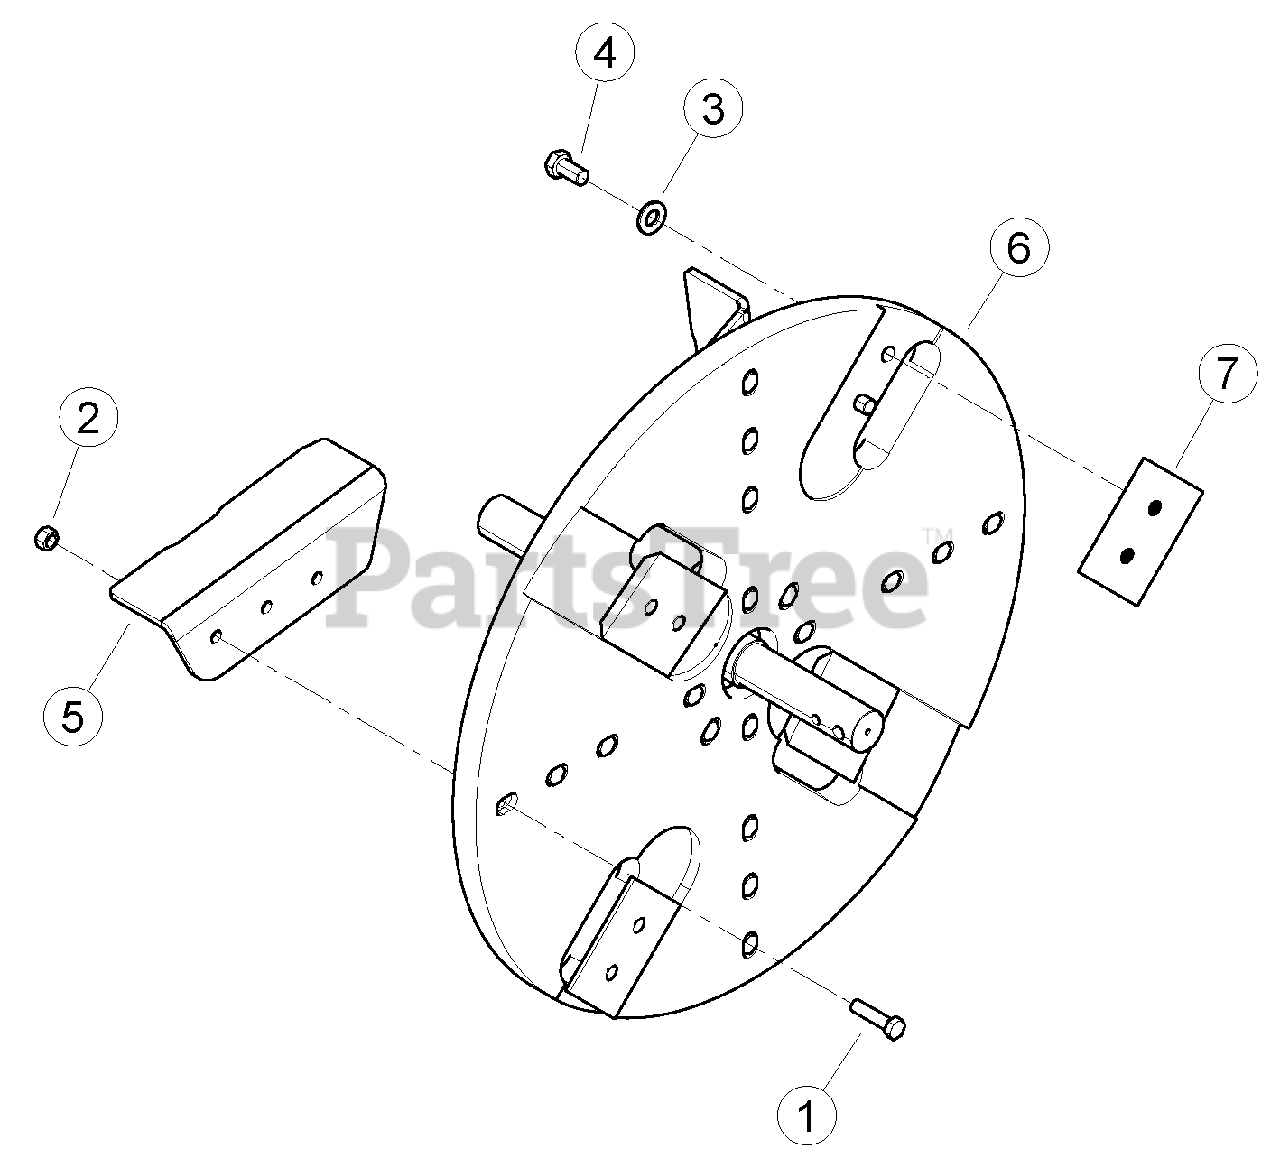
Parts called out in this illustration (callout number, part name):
1	BOLT, 1/2-13 X 2 GR5 HEX CAPSCREW
2	NUT, 1/2-13 GR5 CENTERLOCK GRB
3	WASHER, 5/8 SAE HARDENED
4	BOLT, M16 X 2.0 X 30 HEX HD W/ PATCH
5	KIT, BIG CHIPPER FORMED PADDLES
6	ASSEMBLY, 9 INCH CHIPPER ROTOR
7	KIT, CHIPPER BLADE
